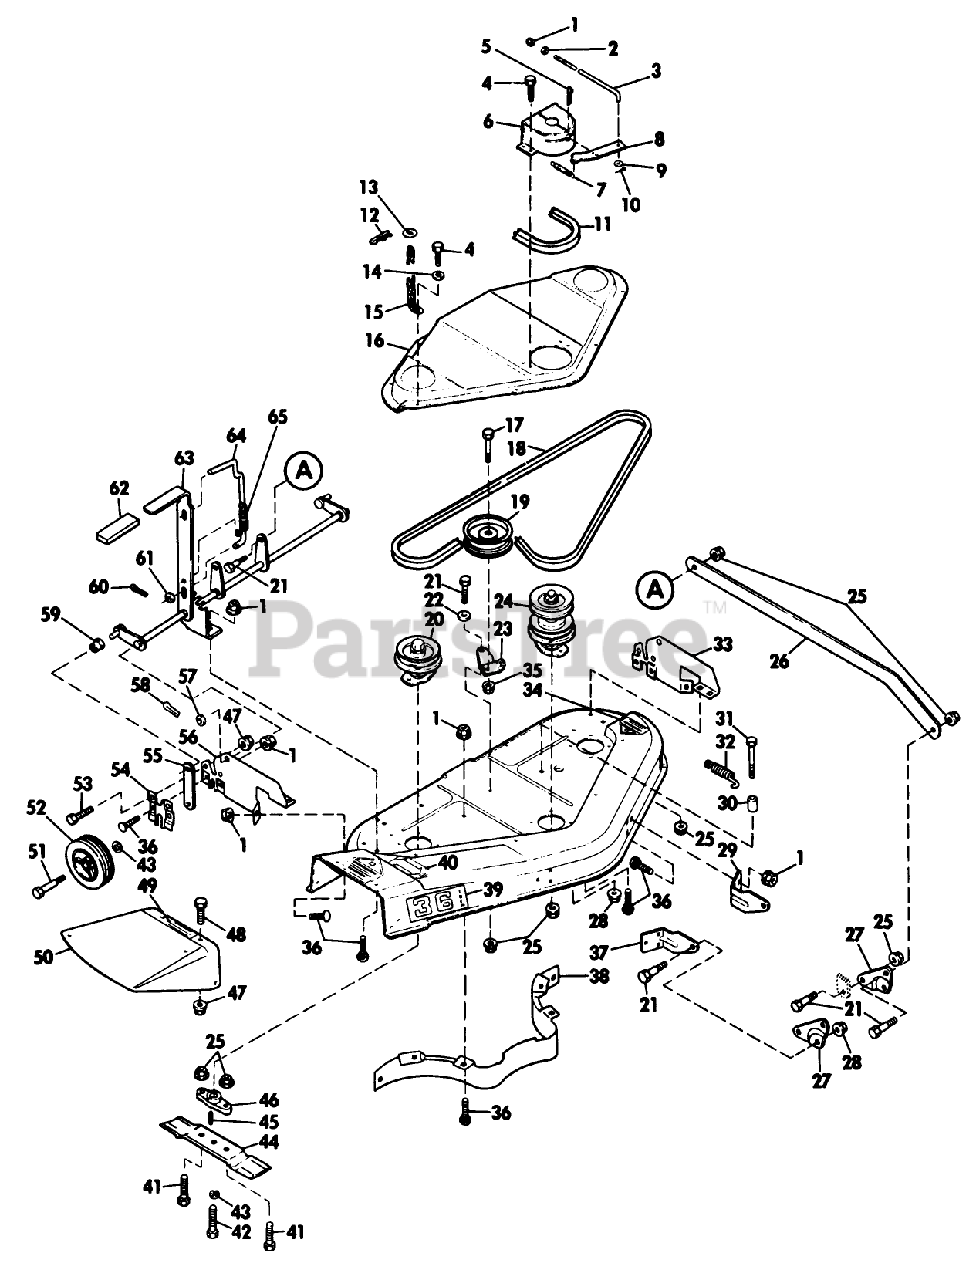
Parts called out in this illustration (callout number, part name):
1	NUT
2	Nut-Jam-Blade Brake Rod
3	Rod-Brake Blade
4	Screw-Belt Cover
5	Clip-Hairpin-Blade Brake Lever
6	Guard Belt
7	Spring-Brake-Blade
8	Lever-Brake Blade
11	V-Belt
13	Washer
14	WASHER
15	Chain
16	Cover-Blade Housing
17	Screw-Idler Pulley
18	V-Belt-Blade Drive
19	Pulley-Idler
20	Spindle Assembly
21	Screw
23	Lever-Idler
24	Spindle Assembly
25	Nut
26	Bar-Parallel
27	Pivot-Blade Housing
28	Locknut-Large Flange
29	Bracket-Blade Housing L.H.
30	Spacer
32	Spring-Idler Lever
33	Bracket-Wheel Mounting L.H.
34	Decal-Caution Pan
36	Bolt
37	Bracket-Wheel Mounting R.H.
38	Baffle-Housing
39	Decal-36 Inch
40	Decal-Blade Positions
41	Screw
42	Screw-Blade
44	Blade
45	Key-Bld-Spindle
46	Adapter-Blade
47	STOP NUT
49	Decal-Caution
50	Deflector
51	Screw
52	Wheel Tire Assembly
54	Retainer-Height Adj. Slide
55	Slide-Height Adjuster
56	Bracket-Wheel R.H.
57	Washer-Height Adjuster
58	Cotter Pin
59	Bushing-Height Adjuster
60	Pin
61	WASHER
62	Grip-Handle
63	Shaft Assembly
64	Latch-Slide
65	Spring-Latch
